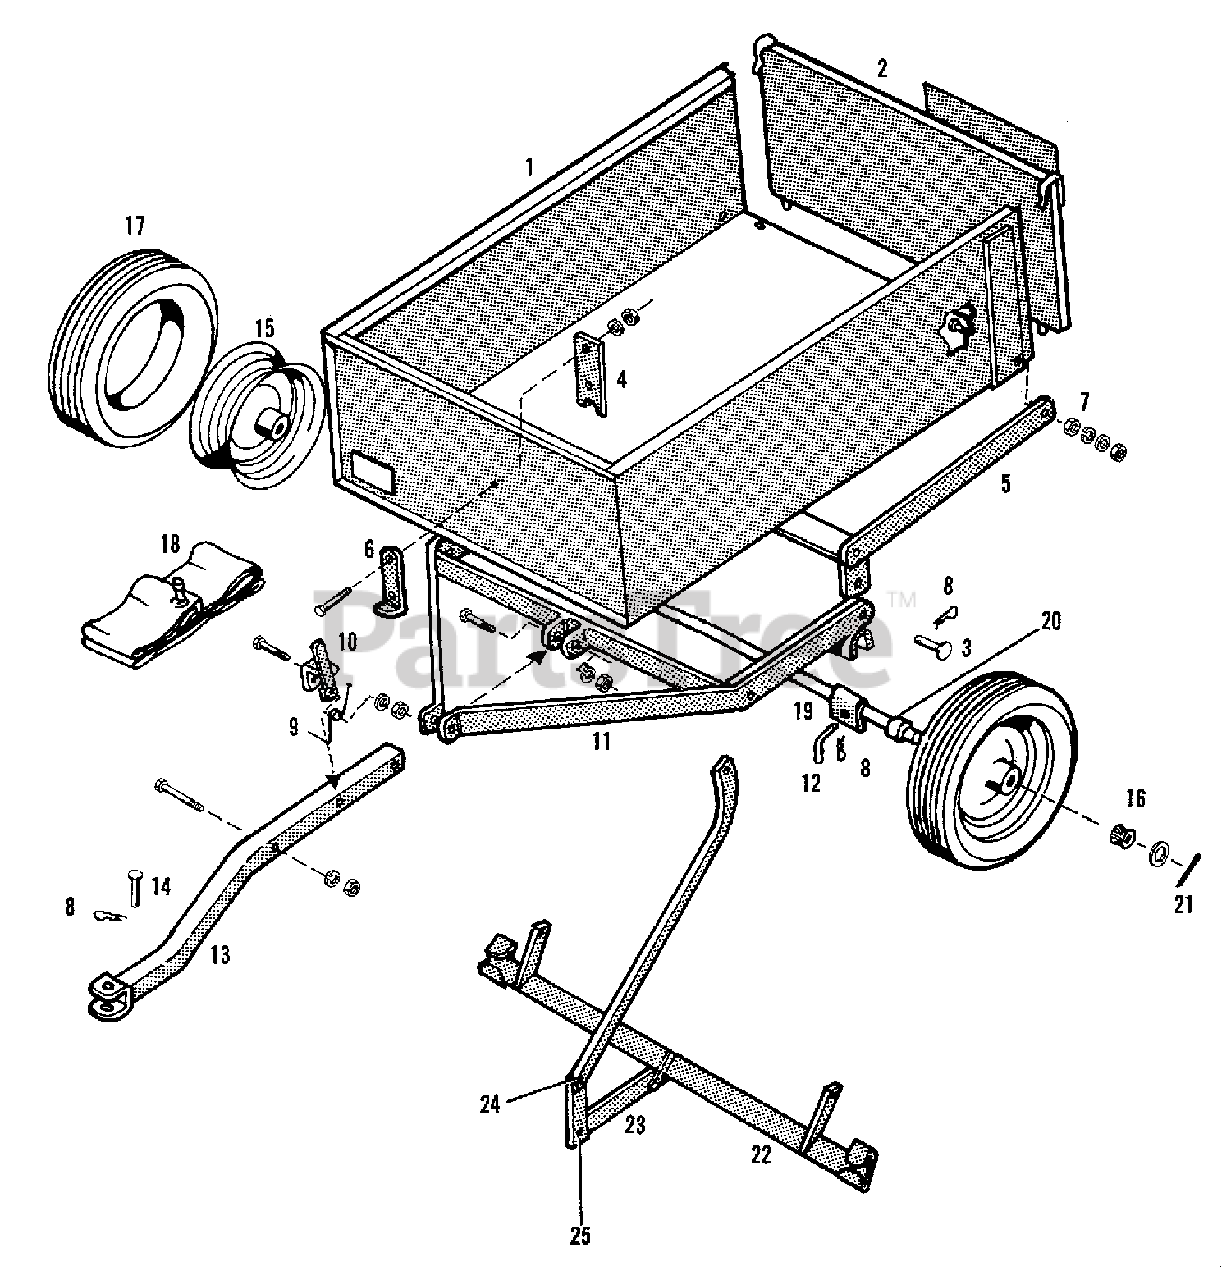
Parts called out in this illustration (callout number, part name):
1	BODY, Trailer
2	GATE, End
3	PIN, Pivot
4	PLATE, Box Guide
5	PIVOT ASSEMBLY, Box
5	CAPSCREW, 3/8NC x 1
5	LOCKWASHER, 3/8
5	NUT, 3/8
5	WASHER, 3/8
6	PLATE, Box Catch
6	CAPSCREW, 3/8NC x 1
6	LOCKWASHER, 3/8
6	NUT, 3/8
8	CLIP, Spring
9	SPRING, Torsion
10	CLEVIS ASSEMBLY, Box
10	CAPSCREW, 3/8NC x 2-3/4
10	WASHER, 3/8
10	NUT, 3/8NC, Centerlock
11	FRAME ASSEMBLY
13	TONGUE ASSEMBLY
13	CAPSCREW, 3/8NC x 2-1/4
13	LOCKWASHER, 3/8
13	NUT, 3/8NC
14	PIN, Inner
19	AXLE ASSEMBLY
20	BEARING, Inner
21	PIN, Cotter, 3/16 X 1-1/2
21	WASHER, 3/4
22	BRAKE ASSEMBLY (Brake Kit)
23	LINK, Brake (Brake Kit)
23	CAPSCREW, 5/16NC x 1-1/2 (Brake Kit)
23	WASHER, 11/32 x 1-1/2 x #12 (Brake Kit)
23	NUT, 5/16NC, Lock (Brake Kit)
24	SPACER (Brake Kit)
25	SPRING, Brake Link (Brake Kit)
